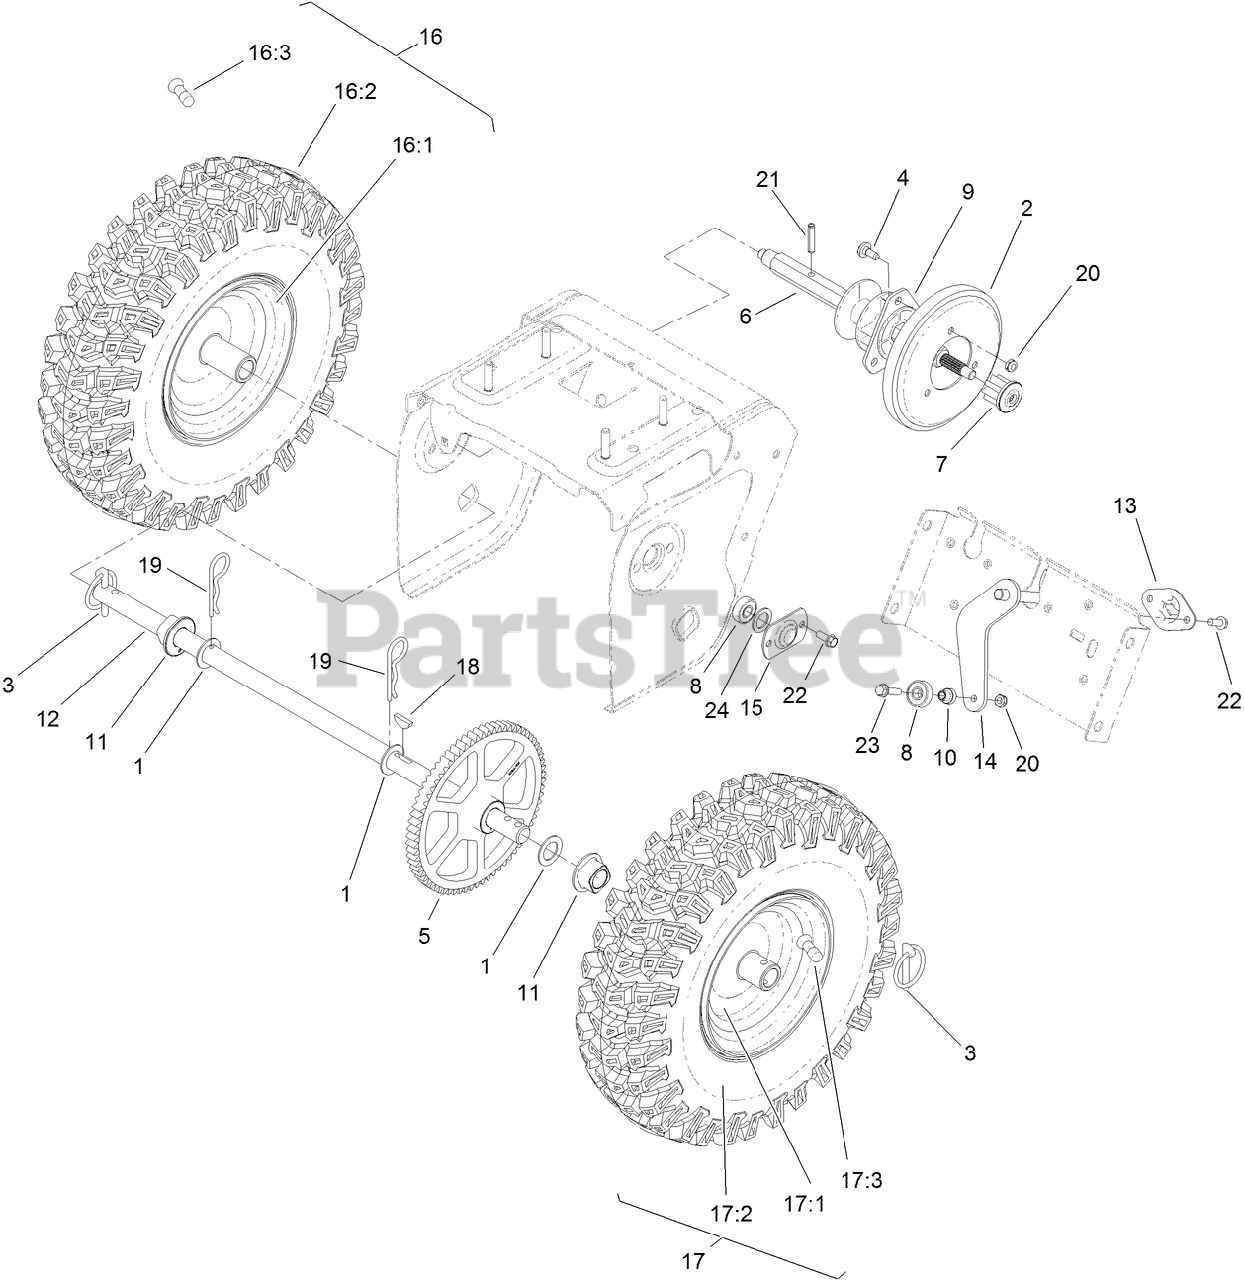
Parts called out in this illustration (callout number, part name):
1	WASHER-THRUST
2	WHEEL-FRICTION
3	KLIK PIN ASM
4	SCREW-SHOULDER
5	GEAR-AXLE
6	SHAFT-HEX
7	GEAR-PINION, 8 TOOTH
8	BEARING-BALL
10	SPACER-PLATE, SHIFT
11	BUSHING-AXLE
13	RETAINER-PLATE, SHIFT
14	SHIFT PLATE ASM
15	RETAINER-BEARING
18	KEY-WOODRUFF
20	NUT-LOCK, NI
21	PIN-ROLL, SLOTTED
22	SCREW-HWH
23	SCREW-HWHTF
24	WASHER-RUBBER
